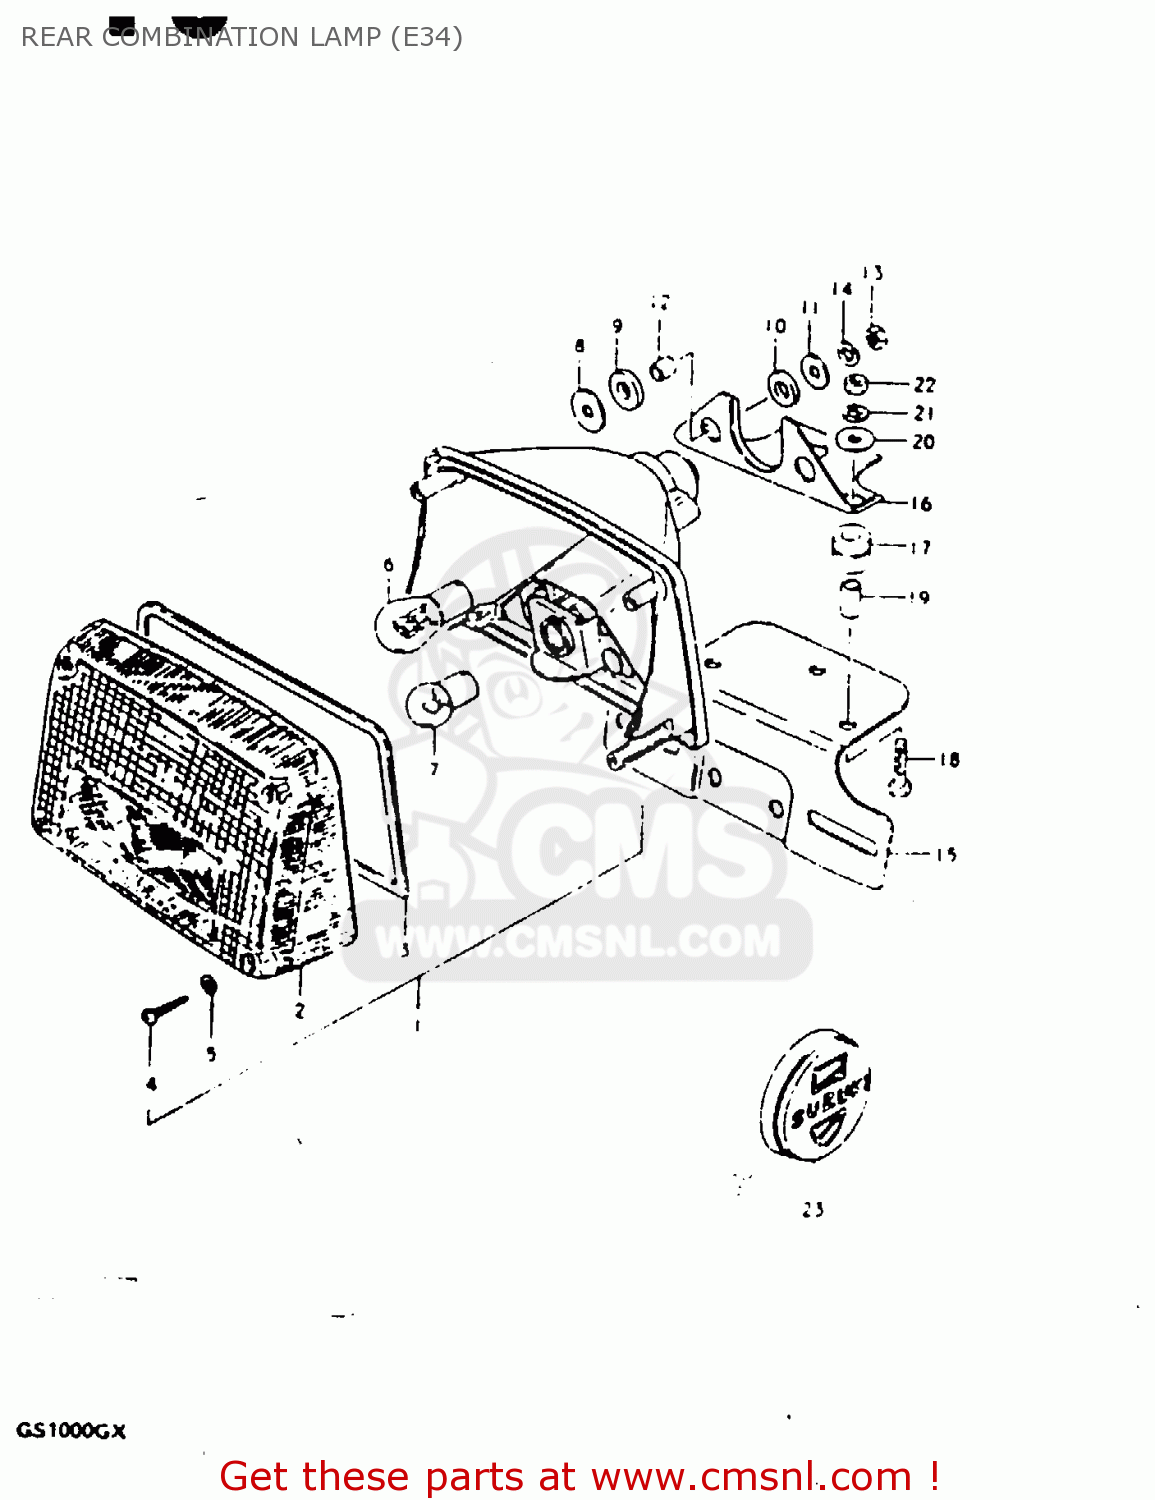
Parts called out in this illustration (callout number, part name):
1	LAMP, REAR COMBINATION
2	LENS
3	GASKET (NAS)
4	BOLT
5	GASKET (NAS)
6	BULB(12V21/5W)
7	BULB
8	WASHER
9	CUSHION
10	CUSHION
11	WASHER(6,5X22X1.6)
12	SPACER(6.1X9X7.5)
13	NUT
14	LOCK WASHER
15	BRACKET, LICENCE PLATE
16	BRACKET,LICENSE PLATE
17	CUSHION, BRACKET
18	BOLT
19	SPACER (6.4X9X15.5)
20	WASHER
21	LOCK WASHER
22	NUT
23	EMBLEM, REAR SIDE
